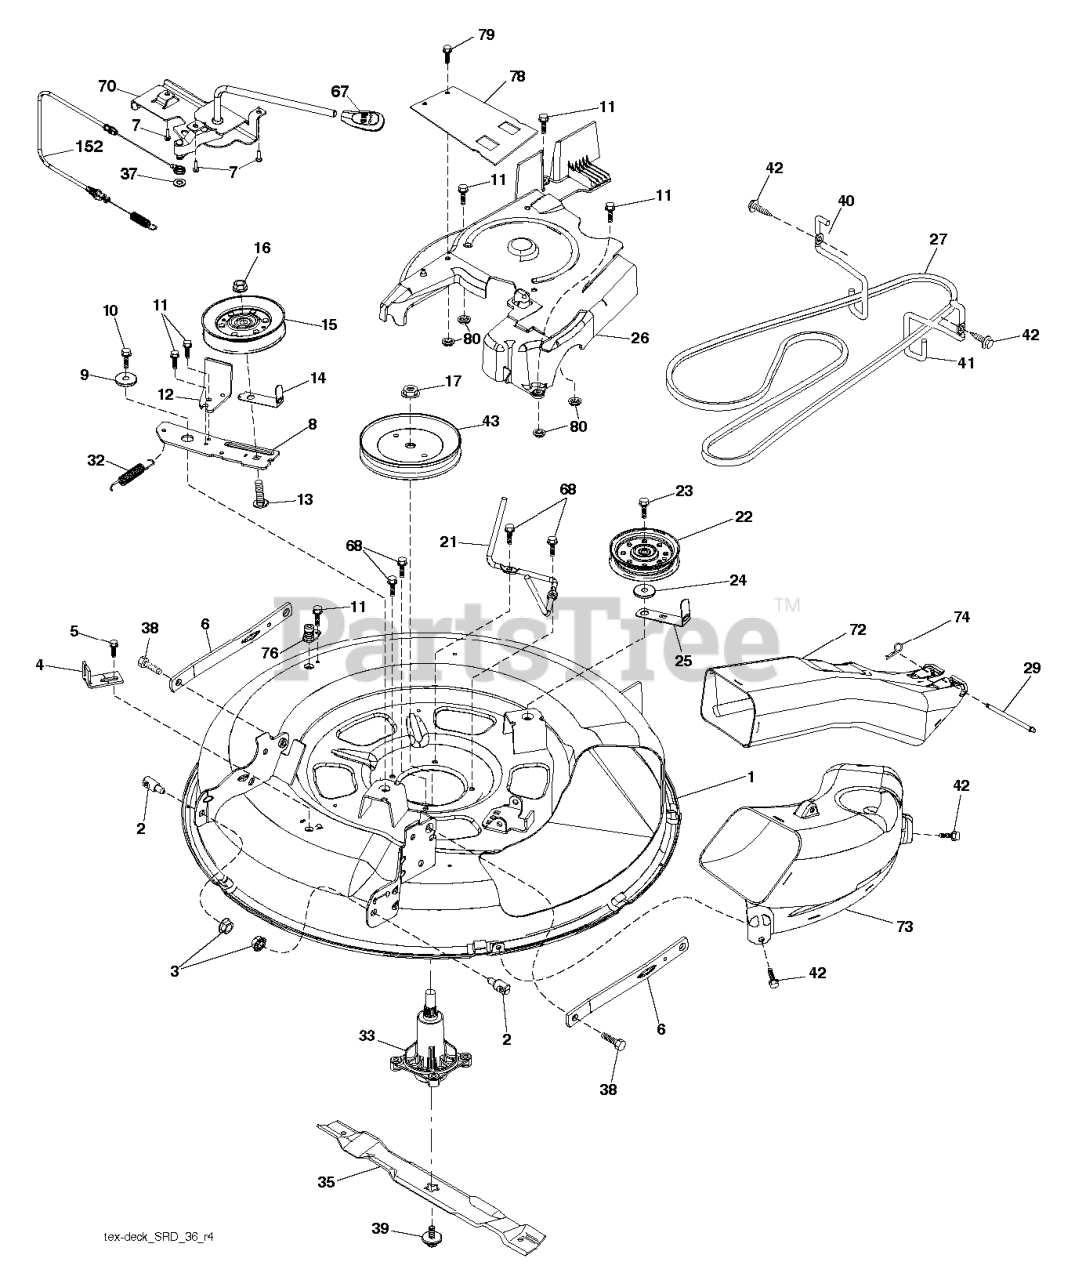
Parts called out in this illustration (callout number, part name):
1	DECK.SVC.WELDMNT.30"419272X418
2	STUD.W/"D"ANTI-ROTATION
4	BRACKET.CLUTCH.CABLE
5	BOLT.5/16HEX.WHS.HD
6	ARMS.SUSP.MOWER.REAR.SRD
8	ARM.IDLER.30"SRD
9	SPACER.RETAINER
10	SCREW 3/8-16X1
11	SCREW.1/4-20X5/8
12	RP ARM.BRAKE.MOWER.38"LH.TEX
13	GSPW Bolts
14	KEEPER, BELT IDLER
15	PULLEY.IDLER.4.25
16	NUT LOCK FLG 3/8-16 UNC
21	KEEPER.BELT.MANDREL.30"
23	BOLT;HEX_3/8-16 X 1.78.CLRZINC
25	KEEPER.BELT.30"SRD
26	COVER.ASM.MANDREL.30"
27	V-BELT.DRIVE.MOWER.30"
32	SPRING RETURN
33	KIT.MANDREL.NONGREASE.TALL
35	BLADE.MOWER.BAGGING.30"
37	WASHER PLAIN WASHER 3/8 X 0.08
38	BOLT.SHOULDER
39	SCREW.SEMS.7/16-20X1.HEX.HEAD
40	KEEPER.BELT.ENGINE.LH.LT.SRD
41	KEEPER.BELT.ENGINE.RH.LT.SRD
42	SCREW, 3/8-16X3/4
43	PULLEY, MANDREL 6.5 PD
67	HANDLE.CLUTCH.CABLE.LT
68	BOLT.HEX.WASHR.HED.313-18X1.19
70	CLUTCH.ASM.MANUAL.LT.PRED
72	CHUTE.UPPER.SRD.30R"
73	CHUTE.LOWER.SRD.30R"
76	PORT.WASHOUT
78	GUARD ARM CLUTCH
80	PALNUT 1/4
152	CABLE.CLUTCH.MANUAL.
